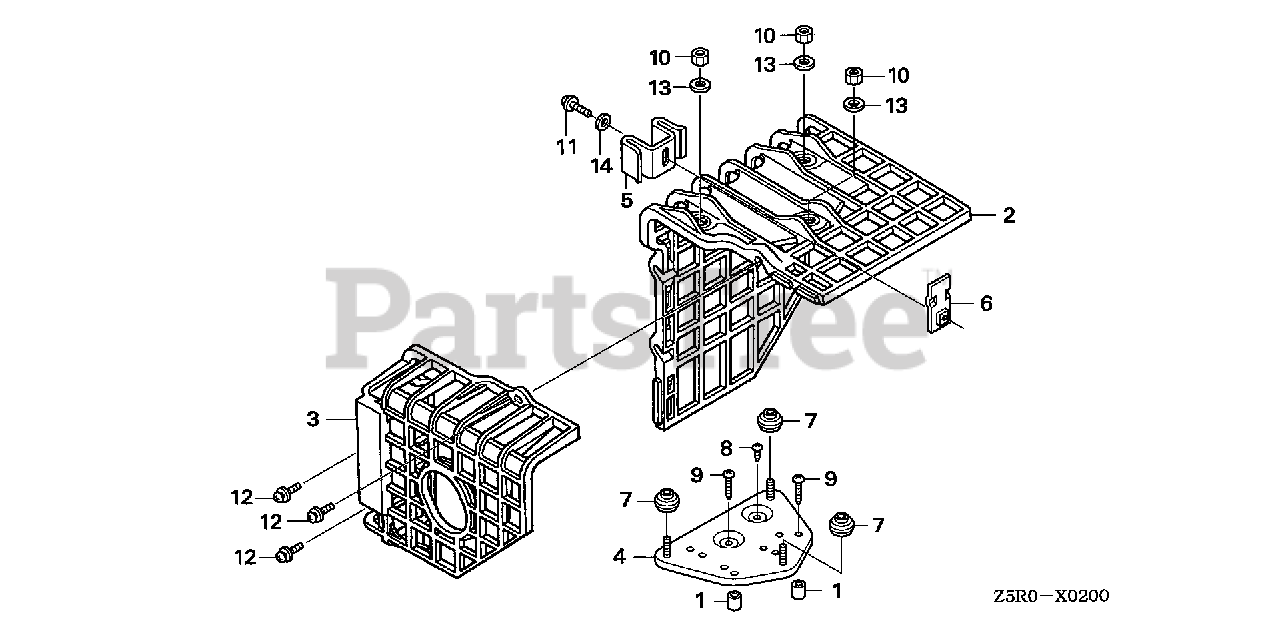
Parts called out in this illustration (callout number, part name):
1	COLLAR, AIR CLEANER HOUSING
2	COVER, MUFFLER
3	COVER, RR. MUFFLER
4	BASE, MUFFLER COVER
5	STAY, MUFFLER COVER
6	PLATE, SET
7	SPACER, MUFFLER COVER
8	SCREW, TAPPING (5X8)
9	SCREW, TAPPING (5X25)
10	NUT, HEX. (5MM)
11	SCREW-WASHER (5X12)
12	SCREW-WASHER (6X20)
13	WASHER, PLAIN (5MM)
14	WASHER, SPRING (5MM)
